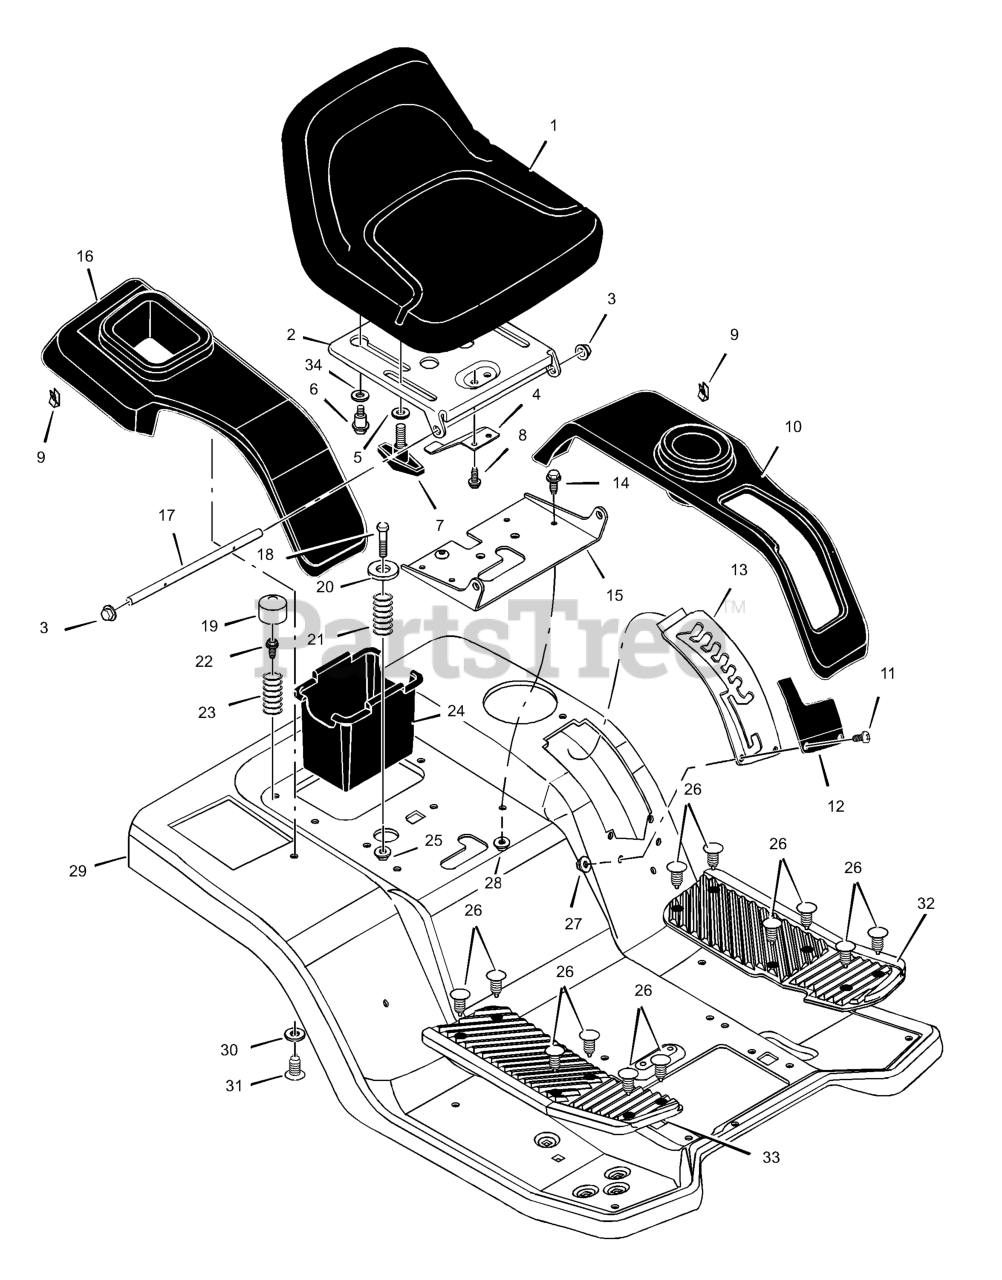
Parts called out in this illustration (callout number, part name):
1	Seat
2	Support, Seat
3	Capo, Push
4	Spring, Leaf
5	Washer
6	Bolt, Shouilder
7	Bolt, Wing
10	Panel, Shoulder-Left
11	Bolt, Shoulder
12	Cover, Detent Lockout
13	Plate, Lift Detent
14	Bolt, Hex
15	Bracket, Pivot
16	Panel, Shoulder-Right
17	Rod, Pivot
18	Bolt, Shoulder
20	Washer, Cup
21	Spring, Compression
23	Spring, Compression
24	Container, Battery
25	Nut, Centerlock
26	Fastener, Panel
27	Locknut
28	Nut, Nylock
29	Deck, Seat
30	Washer
32	Mat, Left
33	Mat, Right
34	Washer
